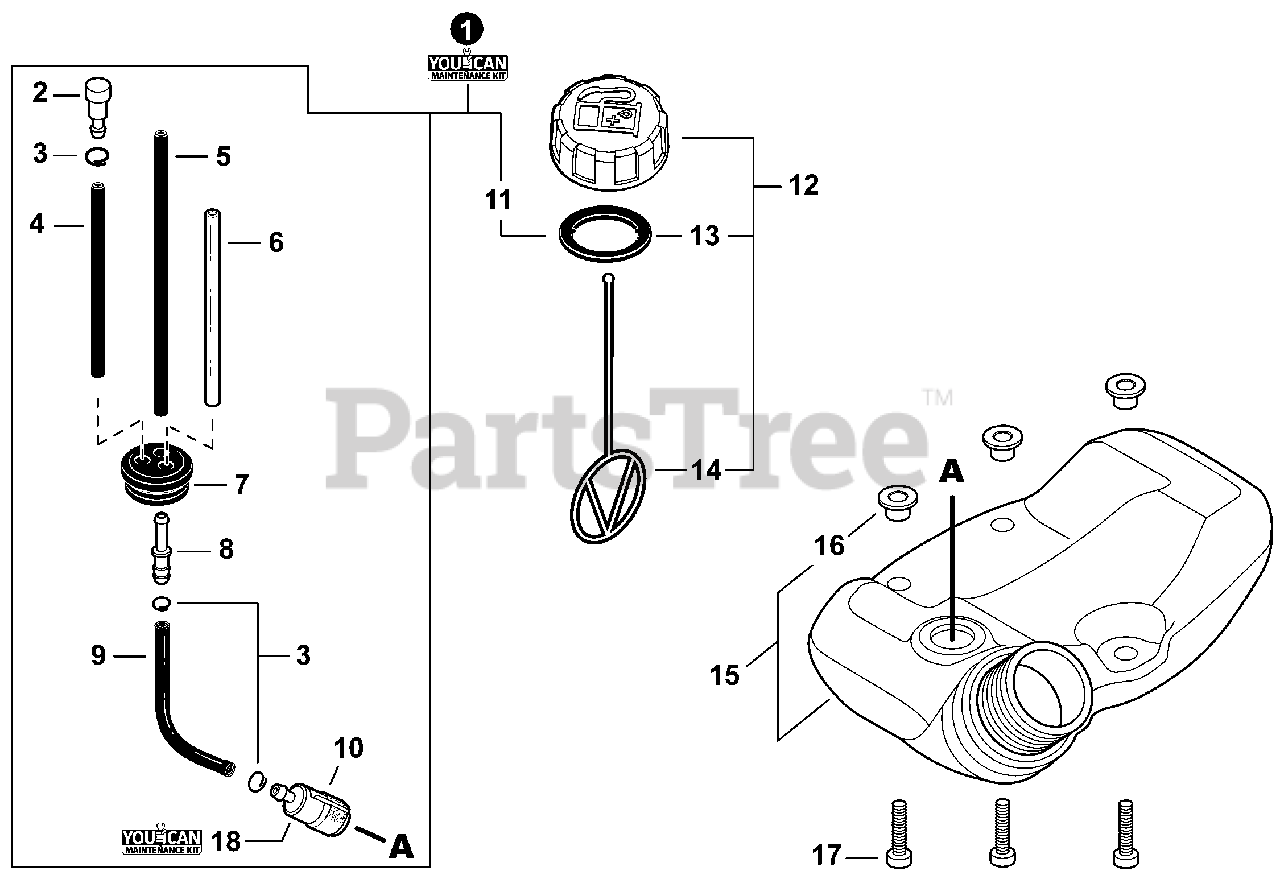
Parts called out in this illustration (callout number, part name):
1	FUEL SYSTEM KIT - YOUCANT
2	VENT ASSY
4	PIPE, FUEL 3x5x90 BLACK
5	PIPE, FUEL 3x5x74 BLACK
6	PIPE, FUEL 3x6x80 YELLOW
7	GROMMET, FUEL 5
8	CONNECTOR, PIPE 5x3.5
9	PIPE, FUEL 3x5x130 BLACK
10	FILTER, FUEL
11	GASKET, FUEL CAP
12	CAP ASSY, FUEL
13	GASKET, FUEL CAP
14	CONNECTOR, CAP L= 123
15	TANK ASSY, FUEL
16	COLLAR 5
17	BOLT, TORX 5x20
18	TUNE-UP KIT - YOUCANT
